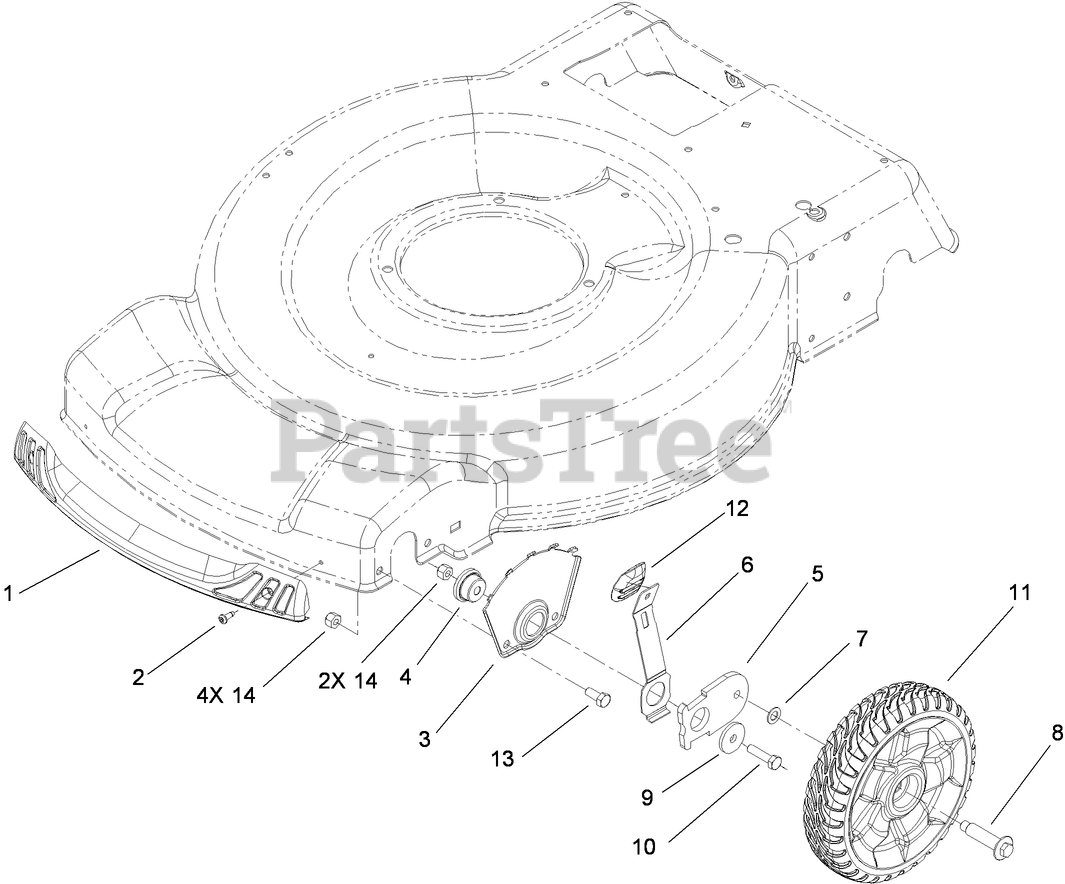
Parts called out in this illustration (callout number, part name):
1	BUMPER
2	SCREW-FORMING, THREAD
3	PLATE-HOC, FRONT
4	BUSHING-MOUNT, HOC
6	ARM-SPRING
7	WASHER
8	BOLT-SHOULDER
9	WASHER-FLAT
10	SCREW-HH
12	KNOB-LEVER, HOC
13	SCREW-HH
14	NUT-LOCK, NI
